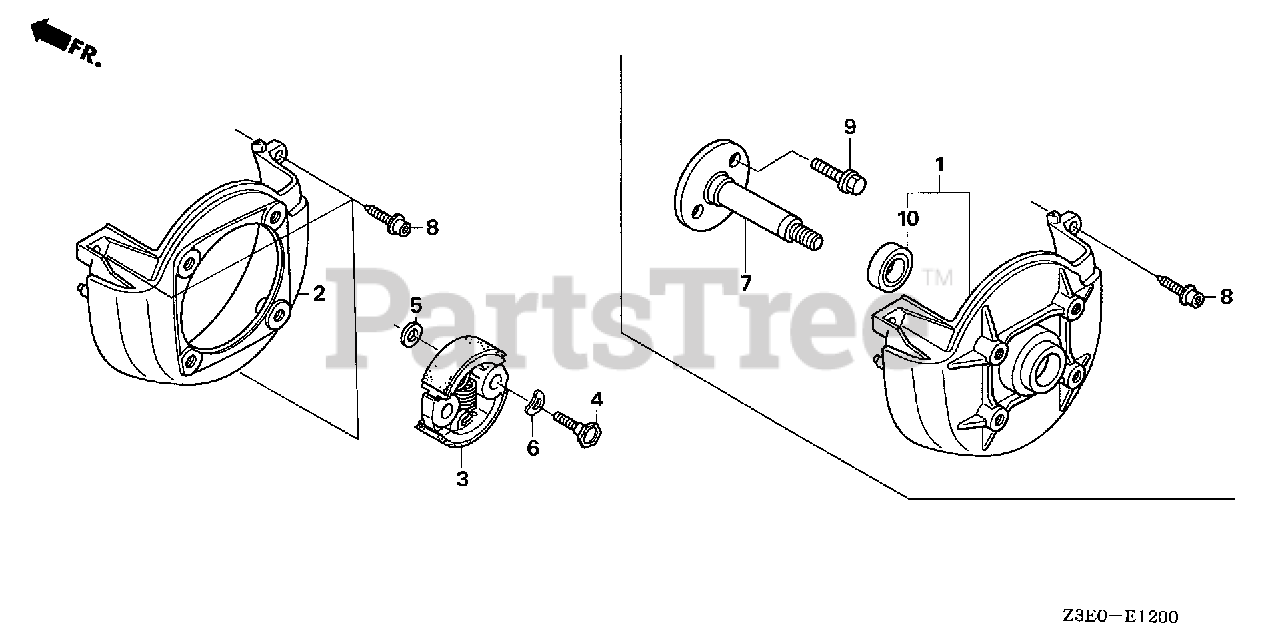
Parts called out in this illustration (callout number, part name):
2	COVER, FAN
3	CLUTCH ASSY.
4	BOLT, CLUTCH (6MM)
5	WASHER, CLUTCH (6X15)
6	WASHER, WAVE (8MM)
8	BOLT, SOCKET (5X20)
